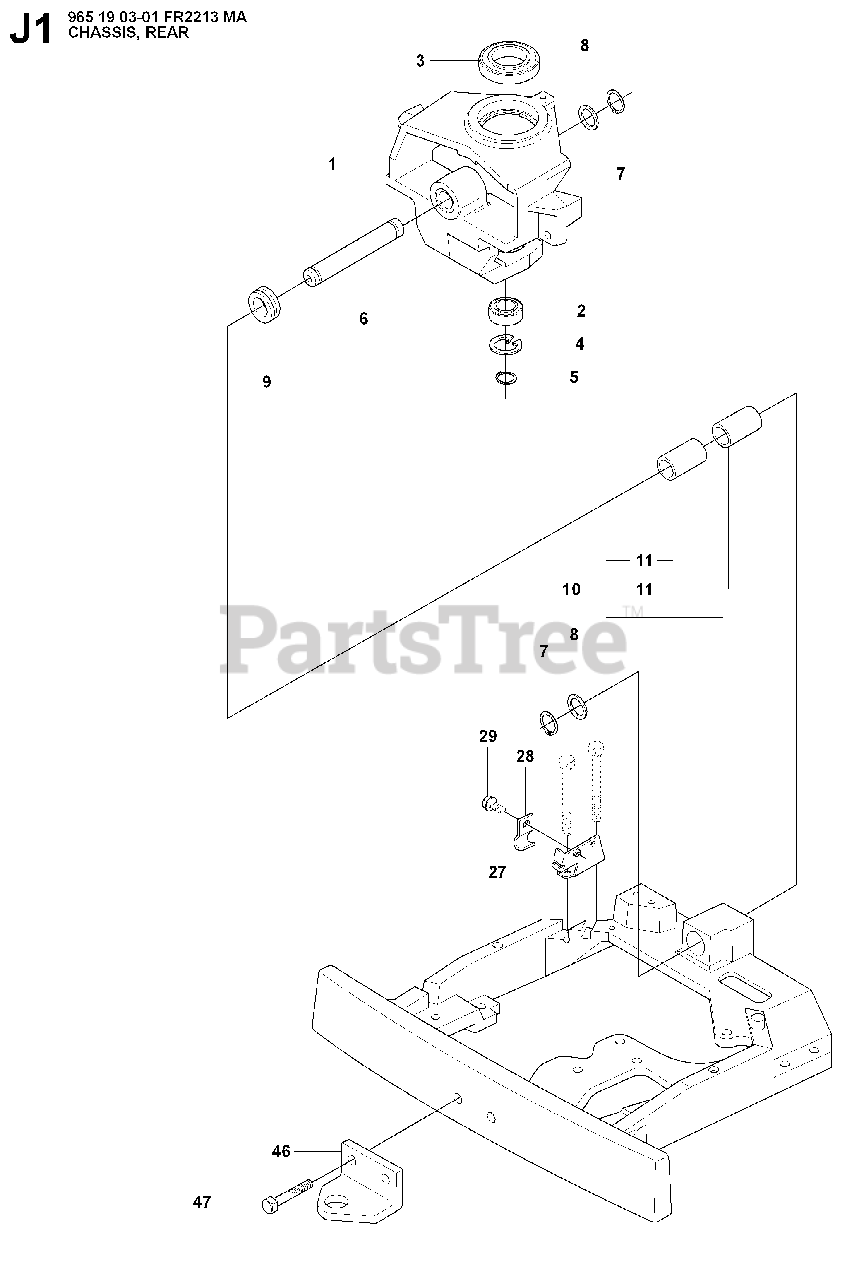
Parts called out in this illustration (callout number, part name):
2	BALL BEARING 6005-2RS
3	BALL BEARING 6010 2RS1
4	CIRCLIP SGH 47
5	RETAINING RING SGA 25
7	RETAINING RING SGA 25
46	DRAW RING
47	SCREW M10X25
